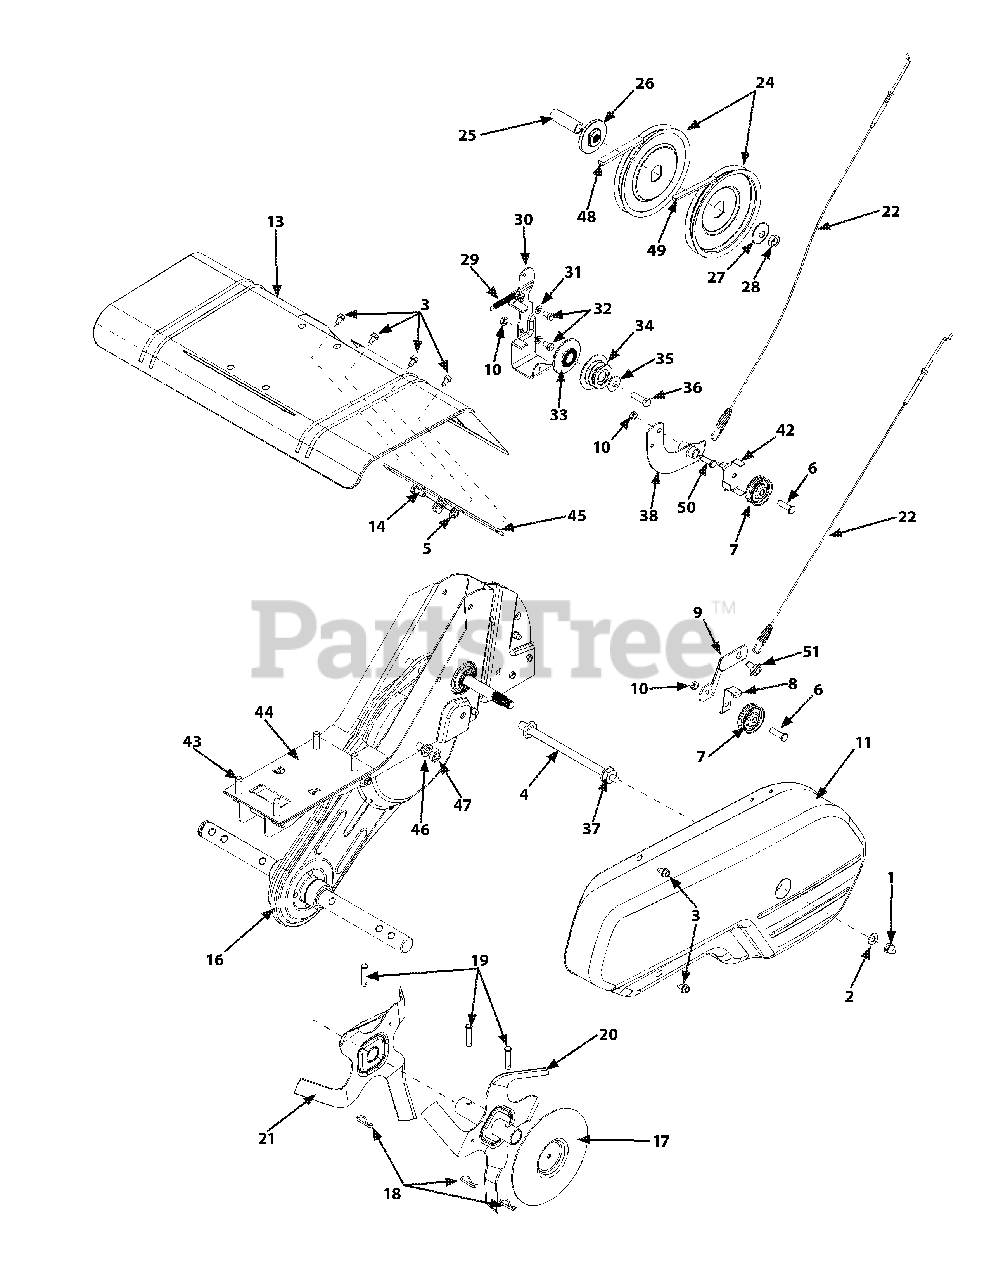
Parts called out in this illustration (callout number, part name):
1	Hex L-Stop Nut, 1/4-28
2	Flat Washer, .266" I.D. x.625" O.D.
3	Hex Washer TT-Tap Screw, 1/4-20 x.5
4	Belt Cover Bolt
5	Hex Flange Top L-Nut,5/16-18
6	Hex Head Screw, 3/8-16 x 1.25" Lg.
7	Flat Idler Pulley, 2.12" O.D.
8	Idler Belt Keeper
9	Idler Bracket
10	Hex Cent. Jam Nut, 3/8-16 Thd.
14	Hex Head Cap Screw, 5/16-18 x.75 Lg
16	Chain Case Assembly Complete
17	Outer Disc Plate Assembly
18	Internal Cotter Pin
19	Clevis Pin
20	Outer Tine Assembly L.H.
20	Outer Tine Assembly R.H.
21	Inner Tine Assembly L.H.
21	Inner Tine Assembly R.H.
22	Forward Clutch Cable
23	Reverse Clutch Cable
24	Fl-Pulley, 6" Dia.
25	Spacer, .64" Dia. x 2.4" Lg.
26	Pulley Mounting Adapter
27	Bell-Wash, .525" I.D. x 1.5" O.D.
28	Hex Jam Nut,1/2-20 Thd.
29	Return Spring
30	Reverse Bracket
31	Lock Washer, 5/16
32	Hex Bolt, 5/16-24 x.625"
33	Engine Inner Half Pulley
34	Reverse Engine Pulley
35	Bell Washer, .396" I.D. x 1/14" O.D.
36	Hex Bolt, 5/16-24 x 1.00"
37	Flangelock Nut, 5/16-18
38	Reverse Arm Assembly
42	Reverse Belt Keeper
43	Hex L-Washer TT-Tap, 3/8 -16 x 1.25"
45	Tine Shield Bracket
46	L-Washer, 7/16" I.D.
47	Hex Nut, 7/16-20 Thd.
48	V-Belt (Forward), 1/2 x 41.9"
49	V-Belt (Reverse), 3/8 x 45.68"
50	Shld. Screw, .498 x 1.445
51	Shld. Screw, .560 x.165
